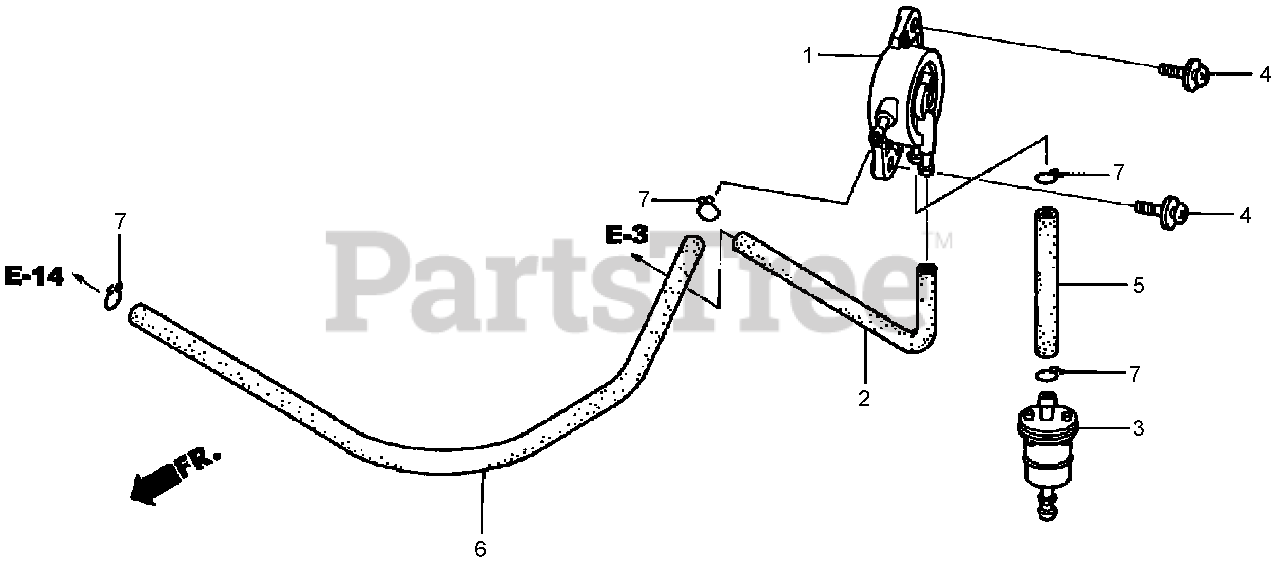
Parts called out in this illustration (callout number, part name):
1	FUEL PUMP ASM
2	TUBE-DIAPHRAGM
3	FILTER-FUEL
4	SCREW-WASHER (5X16)
5	FUEL-HOSE (5.5X8000) (5.5X100)
6	FUEL-HOSE (5.5X8000) (5.5X100)
7	CLIP-TUBE (B10)
